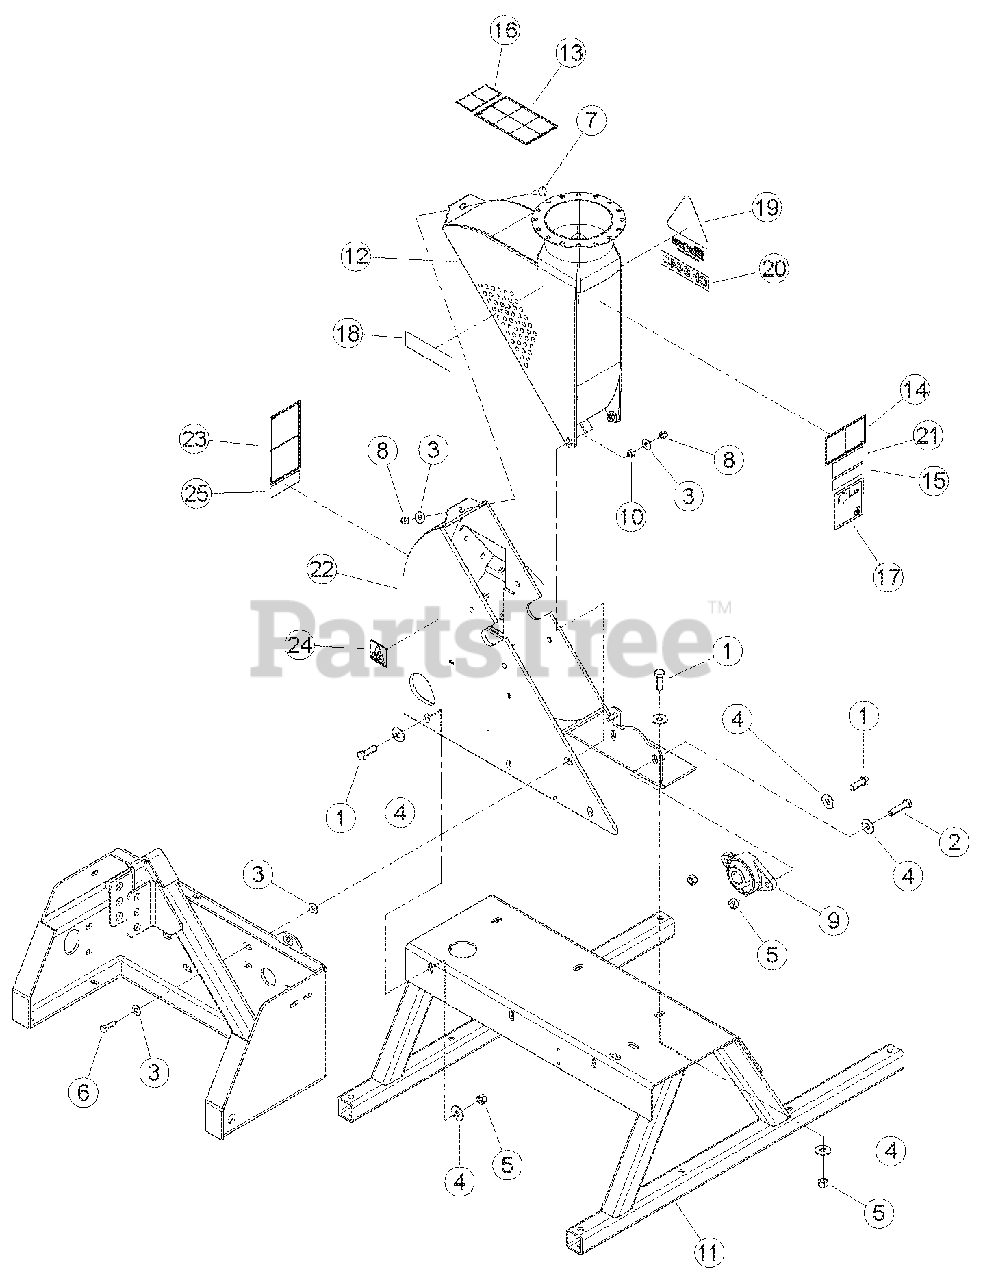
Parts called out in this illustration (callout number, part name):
1	BOLT, 1/2 X 1-1/2 HEX HD GR5 ZP
2	BOLT, 1/2 X 2 HEX HD GR5 ZP
3	WASHER, 3/8 FLAT ZP
4	WASHER, 1/2 FLAT ZP
5	NUT, 1/2 CENTERLOCK GRB ZP
6	BOLT, 3/8 X 1-1/4 HEX HD GR5 ZP
7	BOLT, 3/8 X 1-1/4 CRG GR5 NC ZP
8	NUT, 3/8 NE NYLOCK ZP
9	BEARING, 1-1/4" DIA. 2 BOLT FLANGE
10	BUSHING
11	WELDMENT, PTO CHIPPER STAND
12	ASSEMBLY, CHIPPER TOP, SERVICE PART
13	DECAL, OPERATING INSTRUCTIONS ISO
14	DECAL, DISCHARGE ISO
15	DECAL, 73454S INFORMATION (CE COMPLIANT ONLY)
16	DECAL, MAINTENANCE ISO
17	DECAL, 103 DB (CE COMPLIANT ONLY)
18	DECAL, ECHO BEARCAT 6.82 X 1.90
19	DECAL, CHIP IT
20	DECAL, MODEL CH5540
21	DECAL, ATLANTIC BRIDGE LTD INFO (CE COMPLIANT ONLY)
22	ASSEMBLY, CHIPPER BOTTOM, SERVICE PART
23	DECAL, KNIFE ACCESS ISO
24	DECAL, SHIELD DANGER ISO
25	DECAL, SERIAL NUMBER
